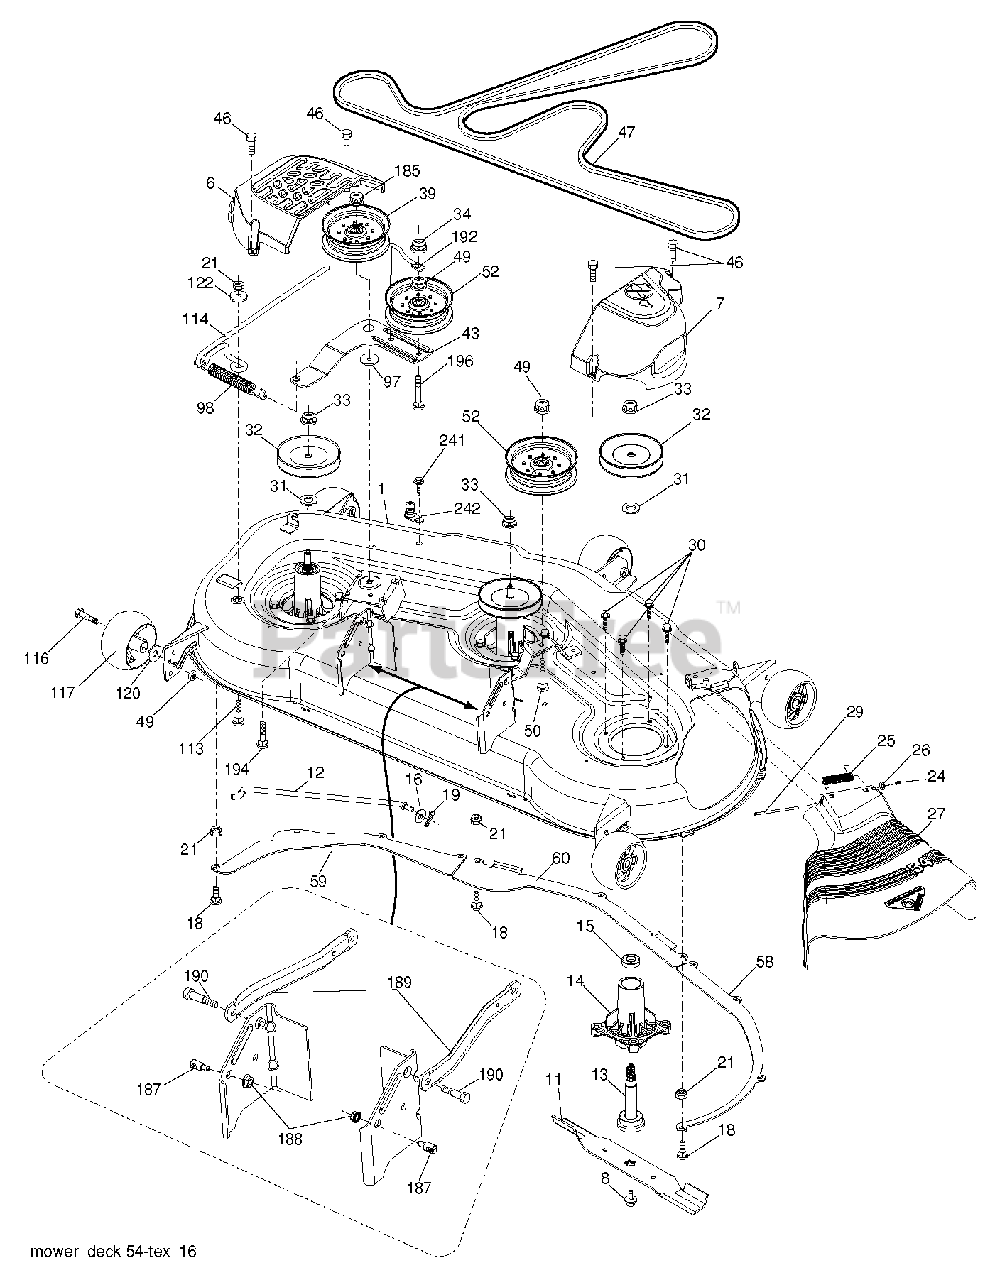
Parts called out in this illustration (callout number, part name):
1	DECK, COMPLETE, 54"
1	DECK, SHELL ONLY, 54"
6	COVER.MANDREL.LH.54"20
7	COVER.MANDREL.RH.54.20
8	BOLT.WASHER.ASM.7/16-2
11	BLADE.BAGGING
11	BLADE.MULCHING
12	ROD.ANTI.SWAY.48/54"K4
13	SHAFT ASM MANDREL
14	HOUSING.MANDREL.4PT.
15	BEARING
16	WASHER
18	BOLT
19	PIN.COTTER.5/16.BOW TI
21	LOCKNUT
24	CAP-SLEEVE LT
25	SPRING, TORSION
26	NUT PUSH M
27	DEFLECTOR
29	ROD.HINGE
30	SCREW, WASHER HEAD
31	WASHER.SPACER.MANDREL
32	PULLEY/MANDREL
33	NUT.FLANGE.LOCK.TOP
34	LOCKNUT
39	RB PULLEY.IDLER.4.50/HUB SPEC
43	ARM.IDLER
46	SCREW.1/4-20X5/8
47	BELT.DRIVE.54."2006
49	NUT LOCK FLG 3/8-16 UNC
50	BOLT
52	PULLEY.IDLER.2006
58	BAFFLE.RIGHT.54"
59	BAFFLE.LEFT.54"
60	BAFFLE CENTER 54" MOWER
97	WASHER
98	SPRING, DECK DRIVE
113	BOLT CRT
114	ROD TENSION RELIEF
116	BOLT.SHOULDER.3/8-16X3-5/8.
117	WHEEL. GUAGE RALLY
120	WASHER
122	BUSHING.RELIEF.TENSION
185	NUT.LOCK.FLANGE.7/16
187	STUD.FASTNER.W/ANTI-ROTATE
188	NUT LOCK HEX FLANGE 5/16-18
189	ARM.SUSPENSION.MOWER
190	BOLT.SHOULDER
192	KEEPER.BELT.IDLER.54"T
194	BOLT.CARR.SQNK.7/16
196	BOLT
241	SCREW.TT.#10-32X.5.3/8.FLANGE
242	PORT.WASHOUT
242	COUPLING.QUICK CONNECT
